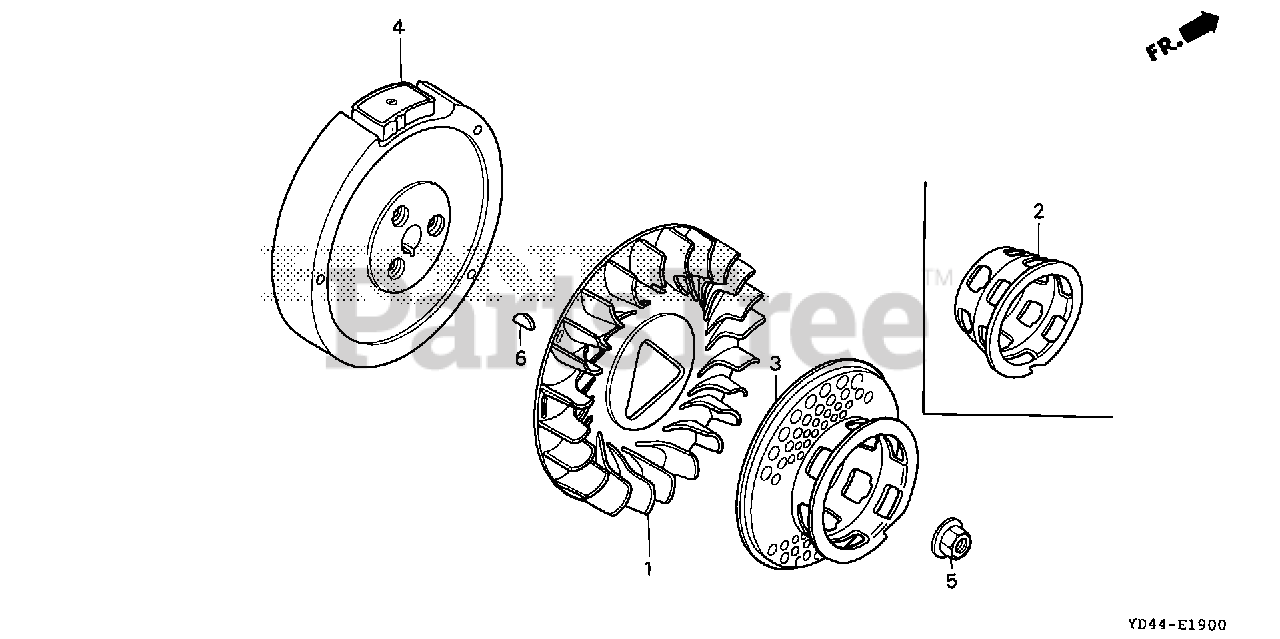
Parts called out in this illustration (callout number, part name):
1	FAN, COOLING
2	PULLEY, STARTER
3	PULLEY, STARTER (SCREEN GRID)
4	FLYWHEEL
5	NUT, SPECIAL (16MM) (1)
5	NUT, SPECIAL (16MM)
6	KEY, SPECIAL WOODRUFF (25X18)
